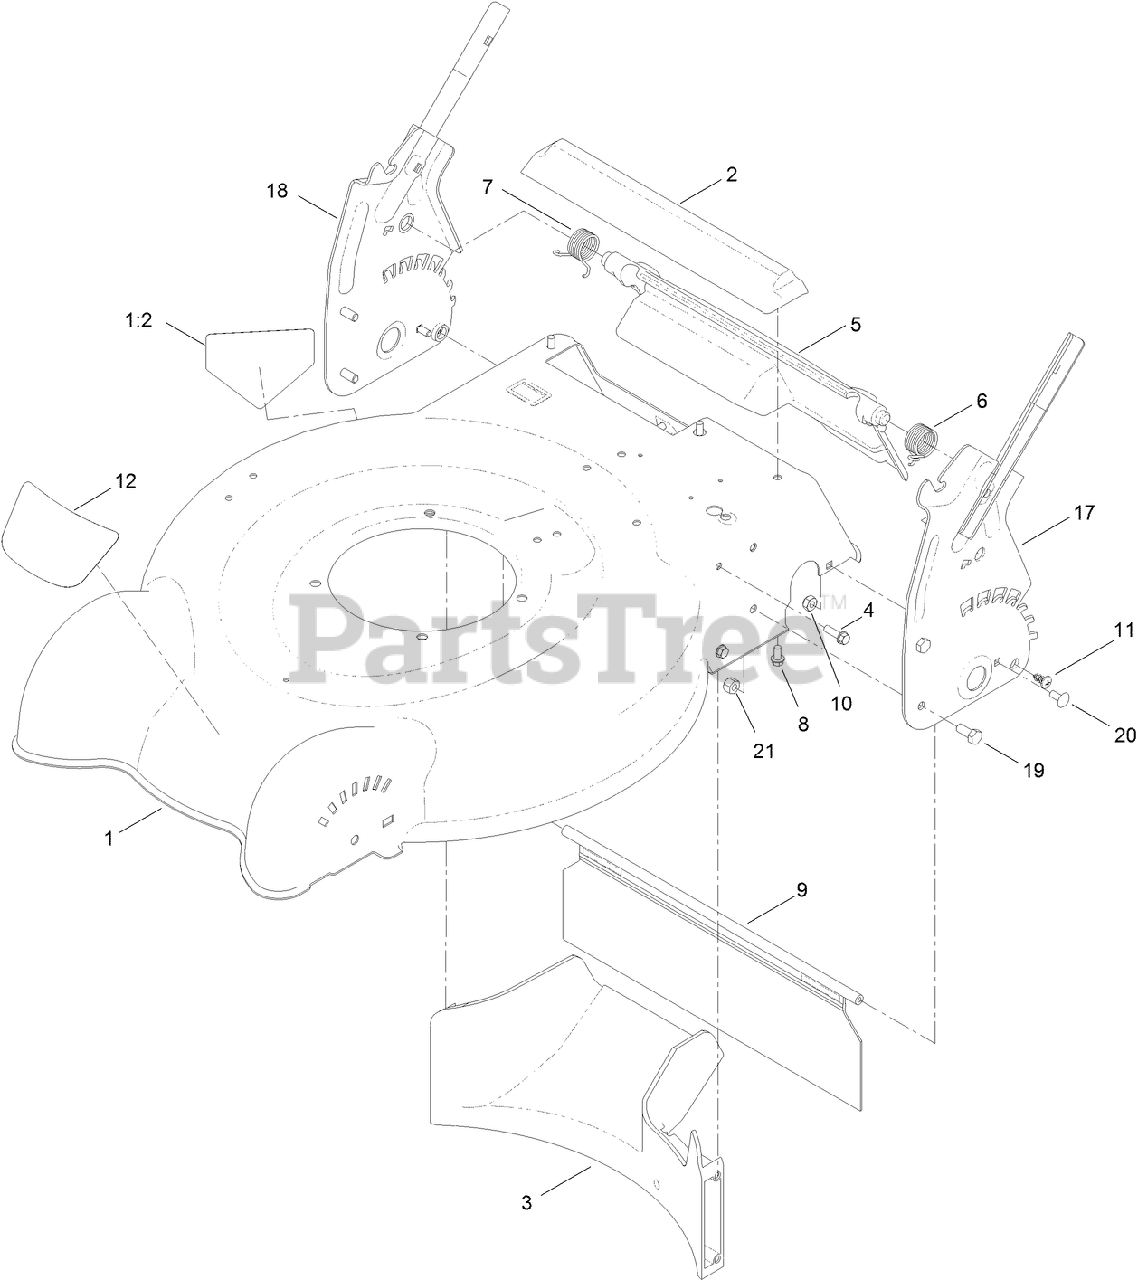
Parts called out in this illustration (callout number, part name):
1	HOUSING ASM
1:2	DECAL-DANGER
2	CHUTE-REAR
3	BAFFLE-REAR
4	SCREW-HWH
5	REAR DEFLECTOR ASM
6	SPRING-TORSION, LH
7	SPRING-TORSION, RH
8	SCREW-PLASTITE
9	SHIELD-TRAILING
10	NUT-LOCK, NI
11	SCREW-PTH
12	DECAL-DECK
19	SCREW-HH
20	SCREW-CARR
21	NUT-LOCK, NI
